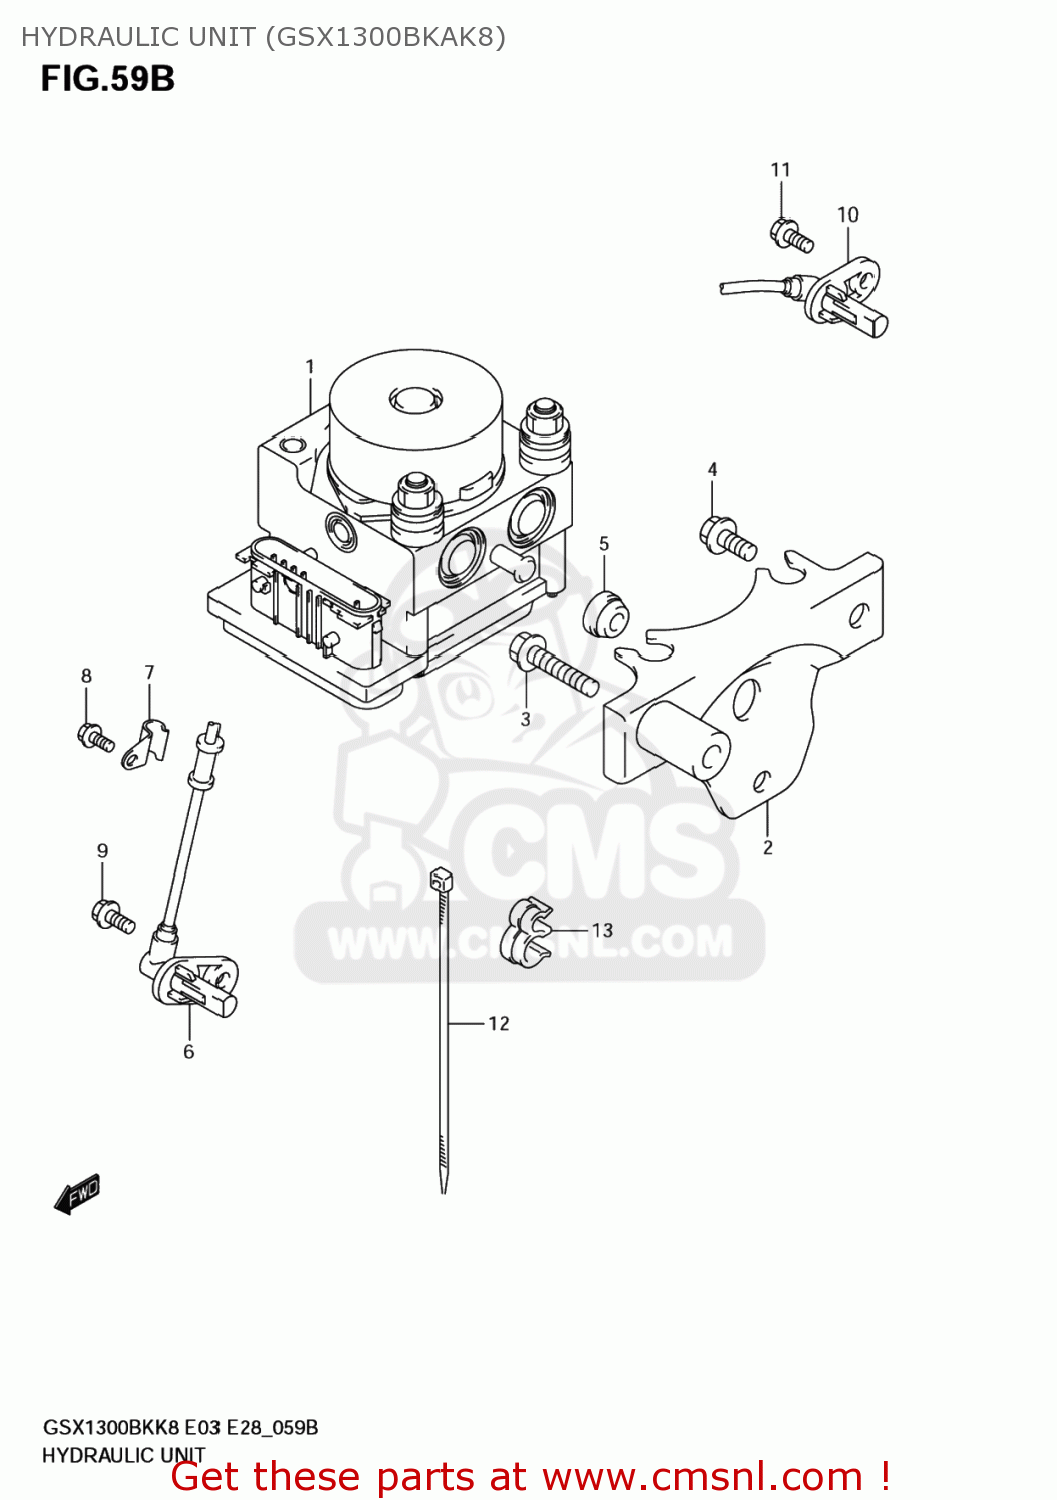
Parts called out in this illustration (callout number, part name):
1	UNIT ASSY,HYDRAULIC ABS
2	HOLDER,HYDRAULIC UNIT ABS
3	BOLT
4	BOLT
5	DAMPER,ACTUATOR MOUNT
6	SENSOR,FR WHEEL ABS
7	CLAMP,ABS SENSOR FR
8	BOLT
9	BOLT
10	SENSOR,RR WHEEL ABS
11	BOLT
12	CLAMP(L:145)
13	CLAMP
